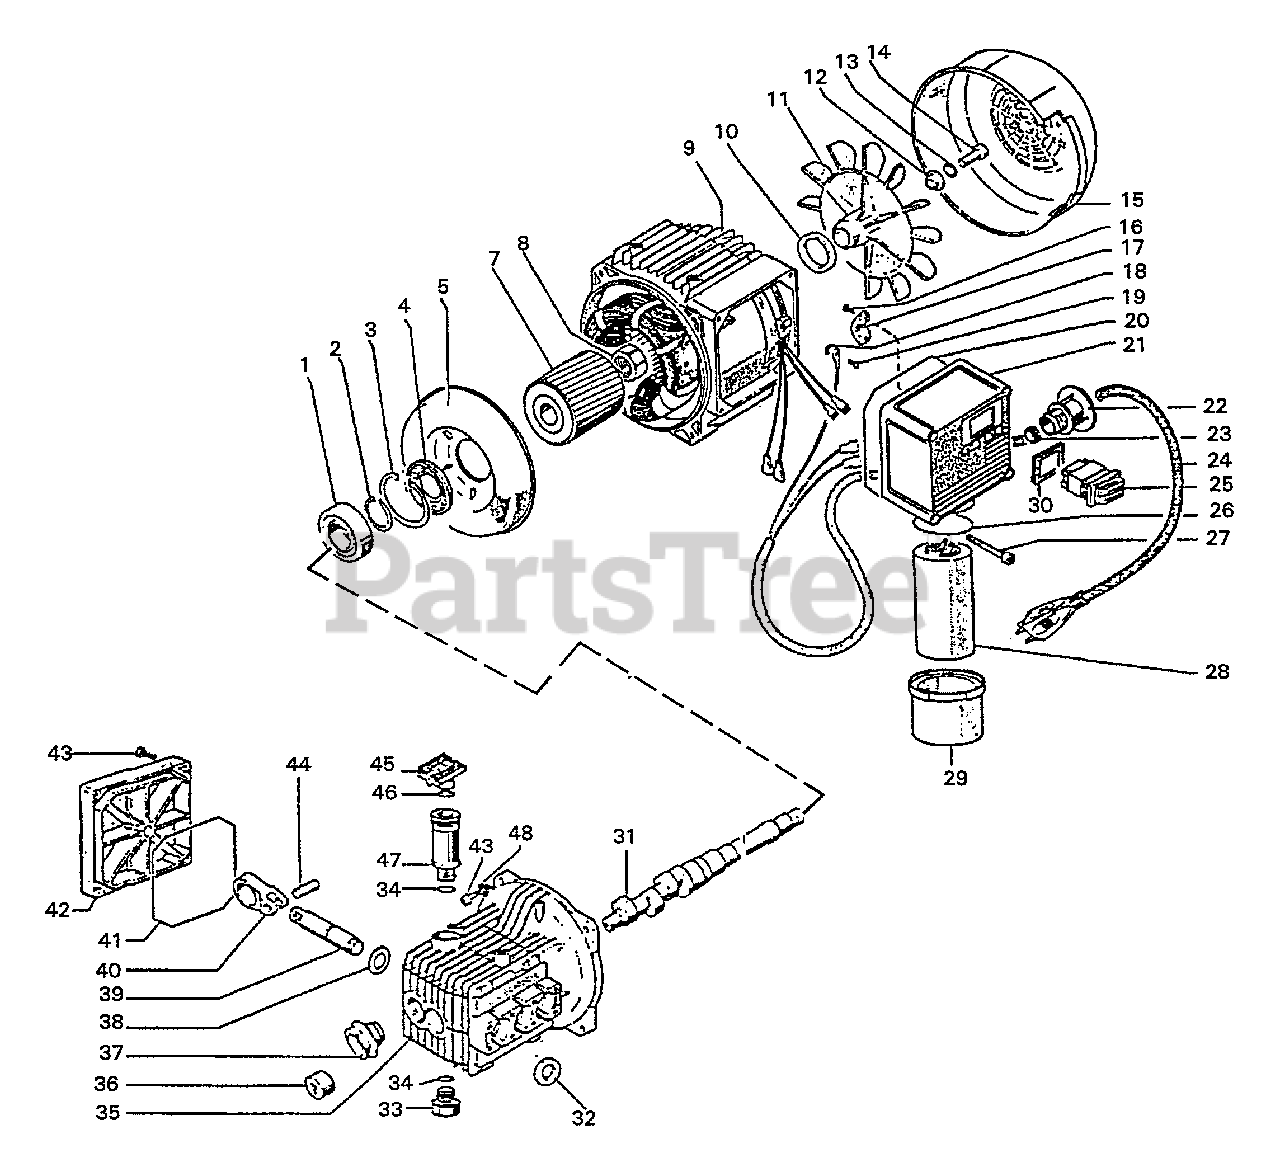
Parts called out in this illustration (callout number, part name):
1	BEARING, BALL
2	RING, RETAINING
3	RING, SNAP
4	SEAL, OIL
7	ROTOR
8	NUT M22
9	STATOR
10	SEAL
11	FAN
12	PLATE
13	WASHER
14	SCREW M8×20
15	COVER, FAN
16	SCREW
17	CLAMP
18	WASHER M5.3
19	SCREW M5×12
20	O-RING
21	COVER, SWITCH
22	HOLDER, CABLE
23	GROMMET, CORD GRIP
24	CABLE, COMPLETE
25	SWITCH, IGNITION
26	O-RING 1.925×.103
27	SCREW M5×65
28	CONDENSER
29	COVER, CAPACITOR
30	GASKET, SWITCH
31	CRANKSHAFT
32	SEAL ASSY, OIL
33	PLUG
34	O-RING 13 95×2 62
35	CRANKCASE
36	NEEDLE, BEARING
37	INDICATOR, OIL LEVEL
38	WASHER, FLINGER
39	PISTON, STAINLESS STEEL
40	ROD, CONNECTING
41	GASKET, COVER
42	COVER, CRANKCASE
43	SCREW M6×25
44	PIN
45	PLUG
46	O-RING 9 92×2 62
47	SPACER, DIPSTICK
48	LOCKWASHER - 6
